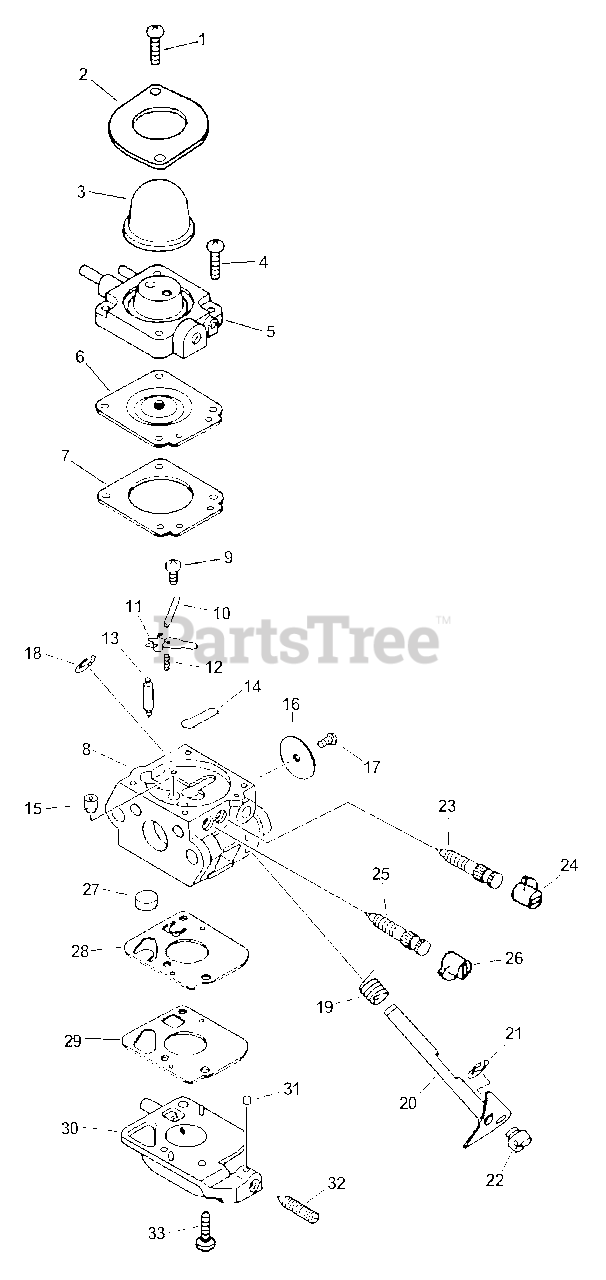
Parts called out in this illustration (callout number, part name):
2	RETAINER, PURGE BULB
3	BULB, PURGE
5	BODY ASSY, PURGE
6	DIAPHRAGM, METERING
7	GASKET, METERING
8	BODY, CARBURETOR
10	PIN, METERING LEVER
11	LEVER, METERING
12	SPRING, METERING LEVER
13	VALVE, INLET NEEDLE
14	PLUG, WELCH
15	NOZZLE, CHECK VALVE
16	VALVE, THROTTLE
19	SPRING, THROTTLE RETURN
20	SHAFT, THROTTLE
23	NEEDLE, MIXTURE
24	CAP, LIMITER - WHITE
25	NEEDLE, HIGH SPEED
26	CAP, LIMITER - RED
27	STRAINER
28	DIAPHRAGM, PUMP
29	GASKET, PUMP
30	COVER, FUEL PUMP
31	PIECE, FRICTION
32	SCREW, IDLE ADJUST
